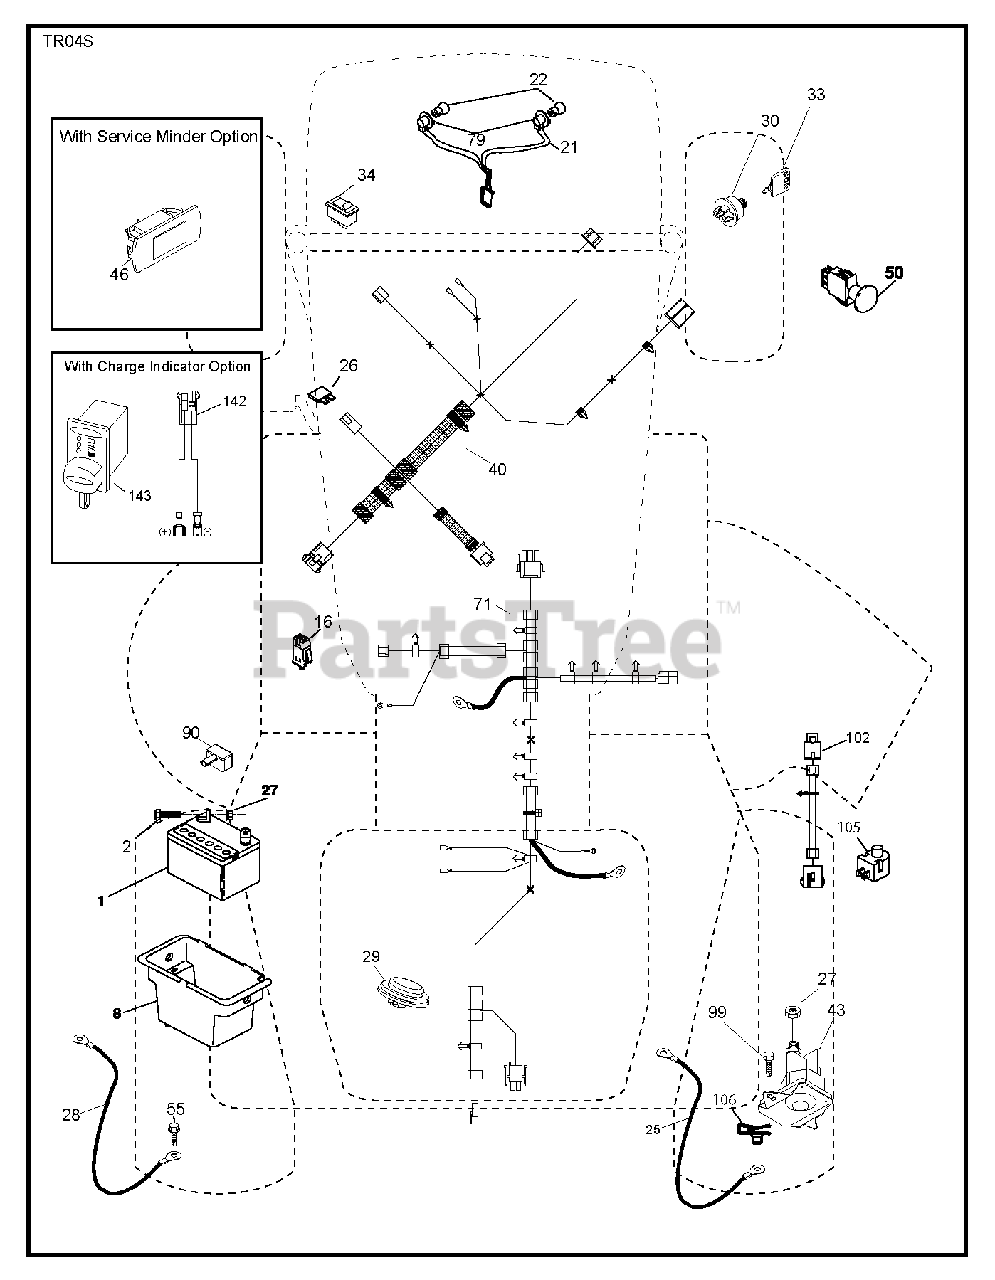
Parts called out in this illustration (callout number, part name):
1	Battery, Dry 30 Amp
2	BOLT.HEX.1/4.X.3/4.DICHROMATE
8	BOX.BATTERY.MNT.REAR.L
16	SWITCH INTERLOOK PUSH-IN
21	HARNESS.LIGHT W/4152J BULBS
25	CABLE.BATT.RED.8GA.17
26	FUSE 20AMP
27	NUT
28	CABLE.BLACK.18"REAR.BA
29	SWITCH.SEAT.DELTA.OPC.
30	SWITCH.IGN.DELTA.W.LGH.ROS
33	KEY.CHAIN.BLISTER.PACK.GEN.USA
40	HARNESS.TEX.DASH.ELEC.REAR BAT
43	SOLENOID.W/BRASS.PLUNGER
46	RP GUAGE.SRVCMNDR.HRMTR.
50	RB PTO.SWITCH.8 TERMINAL.BLACK
55	SCREW 5/16"
71	HARNESS.TEX.CHSSIS.REAR.BATT
79	BULB HOLDER ASM.
90	COVER.TERMINAL.BATTERY
99	SCREW HEXWSHR 1/4-20X3/4
102	HARNESS PIGTAIL PCH TEX ROS
105	REVERSE SWITCH
106	1/4-20 U NUT
